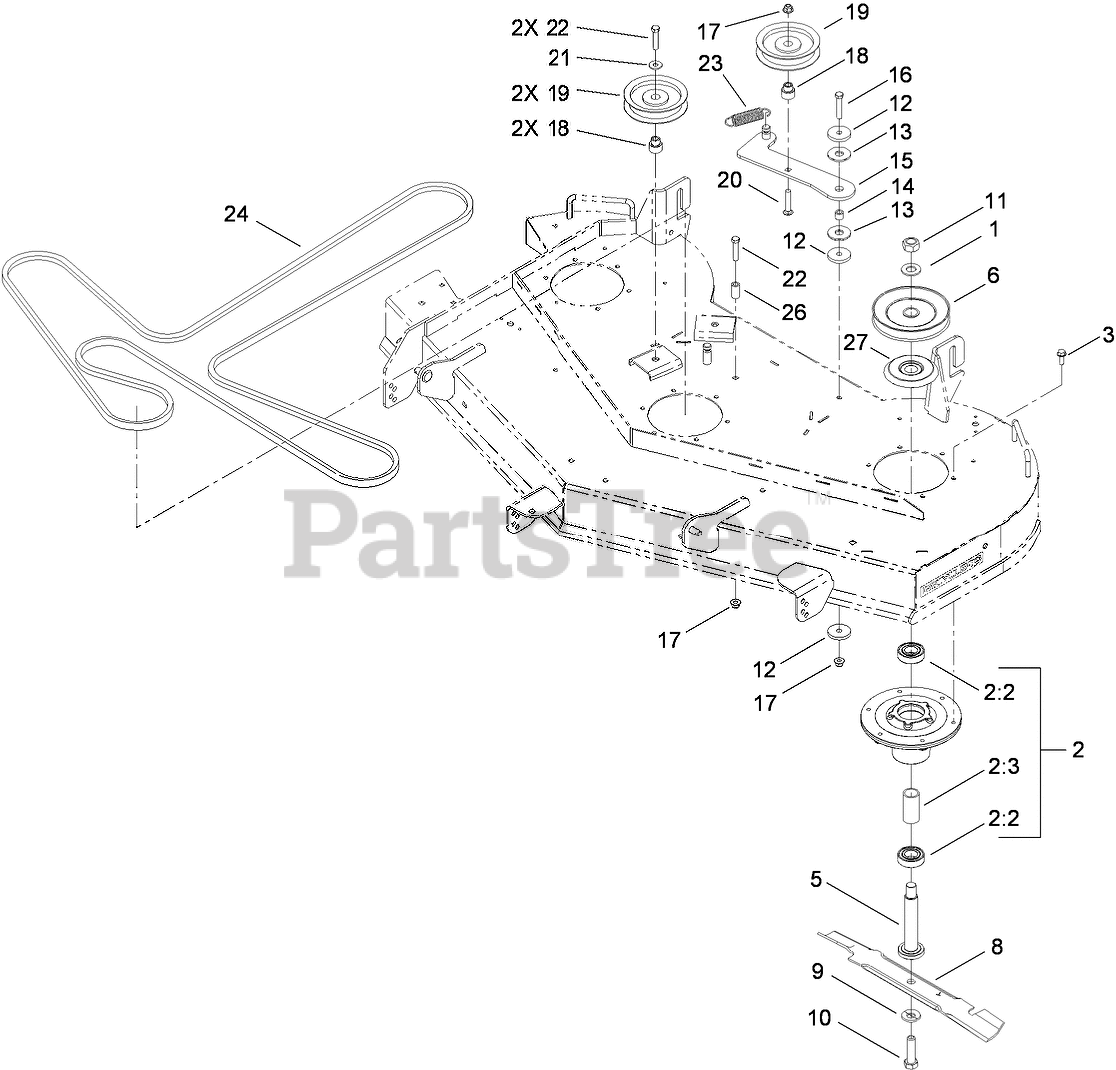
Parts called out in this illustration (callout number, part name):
1	WASHER
2	SPINDLE ASM
2:2	BEARING-BALL
2:3	SPACER-BEARING
3	SCREW-TAPTITE
5	SHAFT-SPINDLE
6	PULLEY
8	BLADE-HI FLO
9	WASHER-BELLEVILLE
10	SCREW-BLADE
11	NUT-HEX
12	WASHER-PLAIN
13	WASHER-FRICTION, COMPOSITE
14	BUSHING-LEVER, LIFT
15	ARM-IDLER
16	SCREW-HH
17	NUT-HF, NI
18	BUSHING-IDLER
19	PULLEY-IDLER
20	SCREW-CARR
21	WASHER-HARDENED
22	SCREW-HH
23	SPRING-EXTENSION
24	V-BELT
26	SPACER
27	SHIELD-BEARING
